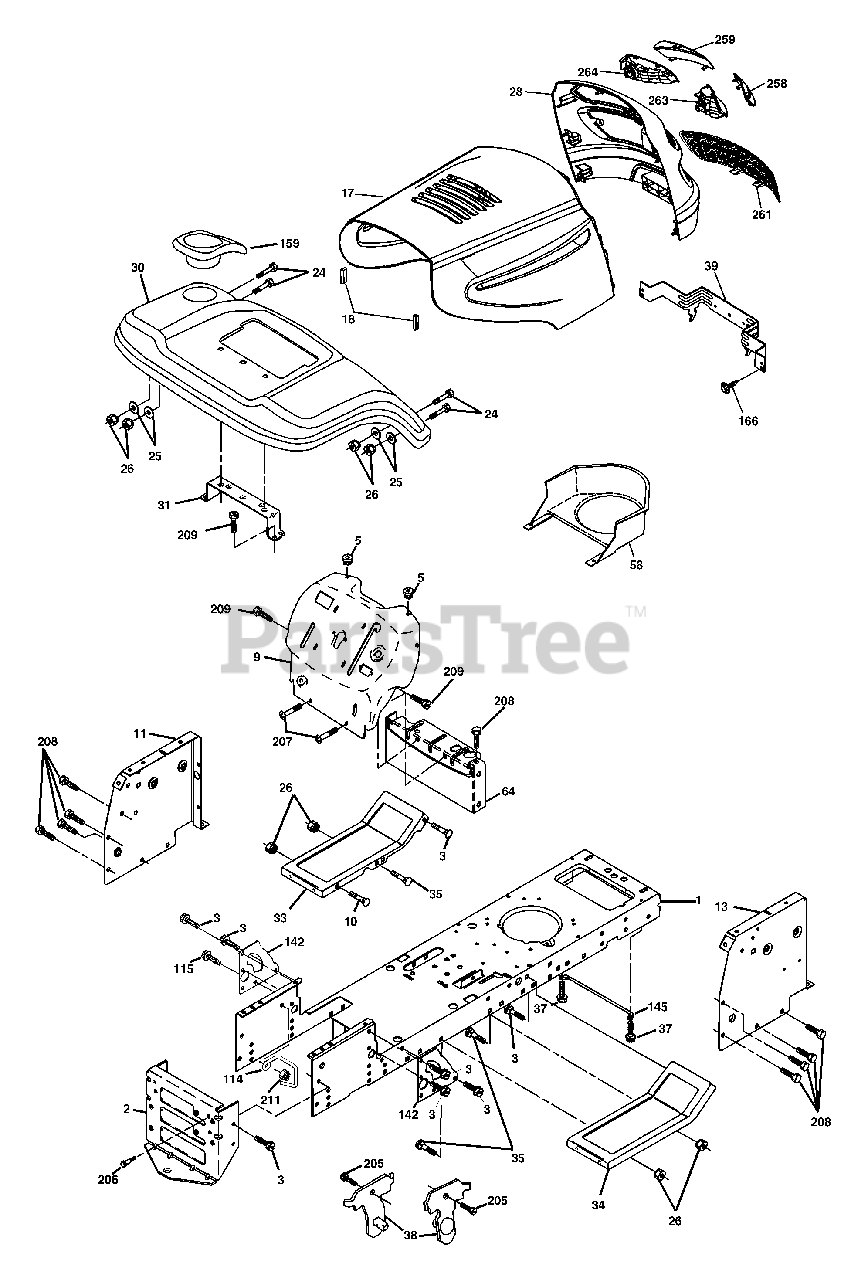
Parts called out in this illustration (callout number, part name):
1	Chassis
2	Drawbar
3	Screw 3/8-16x.75
5	Bumper Hood/Dash
9	Dash P/L
10	Bolt Carriage 3/8-16 x 1
11	Panel Dash Lh
13	Panel Dash Rh
17	Hood
18	Bumper Hood
20	Plate Mtg Battery Fuel Tank Fr
23	Bushing
24	Bolt Fin Hex 3/8-16 x 1 Gr 5
25	Washer 13/32 X 13/16 X 12 Ga
26	Nut Lock Hex W/Ins 3/8-16 Unc
28	Grille Asm.
30	Fender Footrest STLT Pnt
31	Bracket Support Fender
33	Footrest Pnt Lh
34	Footrest Pnt Rh
35	Bolt Rdhd Sht Sqnk 3/8-16 x 3/4
37	Screw Thdrol 6/16-18 x 1/2 TYT
38	Bracket Asm. Pivot Mower Rear
39	Bracket Pivot Laser
58	Duct Air
64	Dash Lower STLT
114	Keeper Belt Rear Lh
115	Screw 3/8-16 x 1-1/4
142	Plate Reinforcement STLT
145	Rod Pivot Chassis/Hood
159	Cupholder
166	Screw Hw Hd Hi-Lo #13-16 x 3/4
205	Screw Thdrol 3/8-16 x 1-1/4
206	Bolt Shoulder 5/16-18
207	Screw Thdrol 5/16-18 x 1/2
208	Screw Thdrol 3/8-16 x 1/2
209	Screw 3/8-16 x 3/4
211	Nut Hex Flange Lock
219	Screw 5/16-18 x 3/4
258	Lens Grille RH
259	Lens Grille LH
263	Bezel Grille LH
